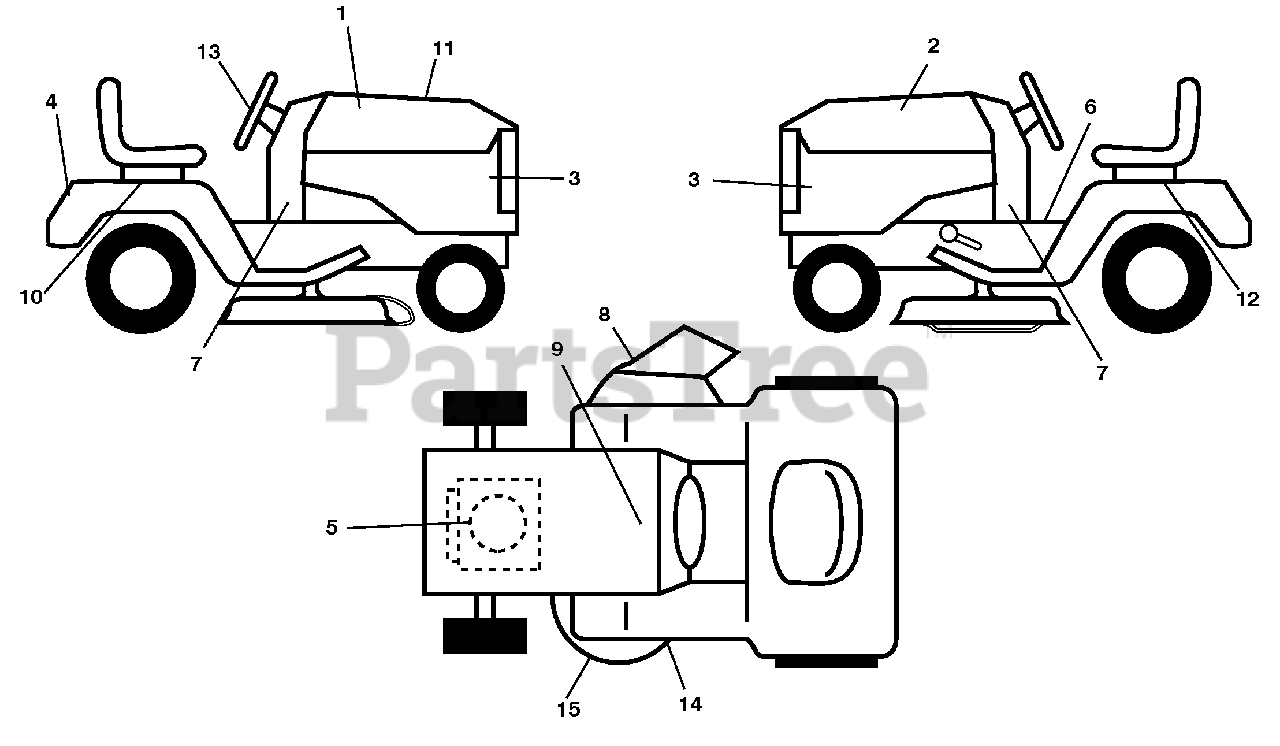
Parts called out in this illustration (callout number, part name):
1	Decal, Hood RH
2	Decal, Hood LH
3	Decal, Side Panel
4	Decal, Fender
5	Decal, Engine
6	Decal, Fender Operator's
7	Decal, Lower Dash
8	Decal, Warning
9	Decal, Battery Dnge/Poi
10	Decal Fender RH
11	Decal, Replacement
12	Decal Fender LH
13	Decal, Steering Wheel
14	Decal, Mower Schematic
15	Decal, Caution
15	Pad Foot Pedal Control
15	Decal, Bypass
15	Pad, Footrest, LH
15	Manual, Operator's (Eng/French)
15	Manual, Parts
